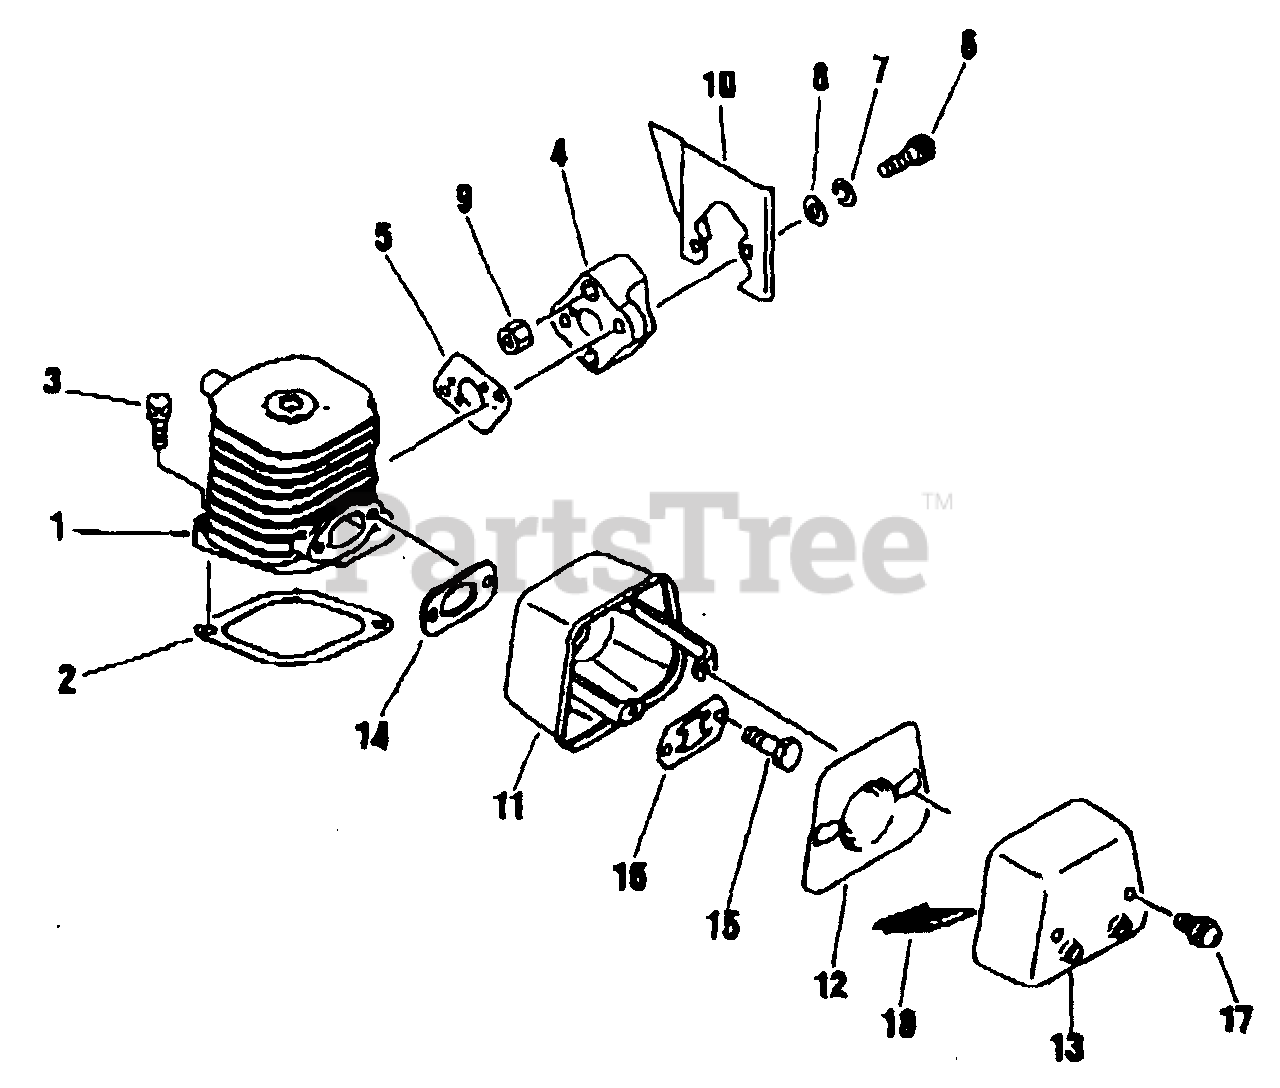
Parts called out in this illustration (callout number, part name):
1	CYLINDER
3	SCREW - 5X20
4	INSULATOR
5	GASKET
6	SCREW - 5X18
7	LOCKWASHER - 5
8	WASHER - 5
9	NUT
10	GUIDE, AIR
11	MUFFLER BASE
12	MUFFLER PLATE
13	COVER, MUFFLER
14	GASKET, EXHAUST
15	BOLT - 5X16
16	LOCKWASHER
17	SCREW - 4X8
18	SCREEN, SPARK ARRESTOR
